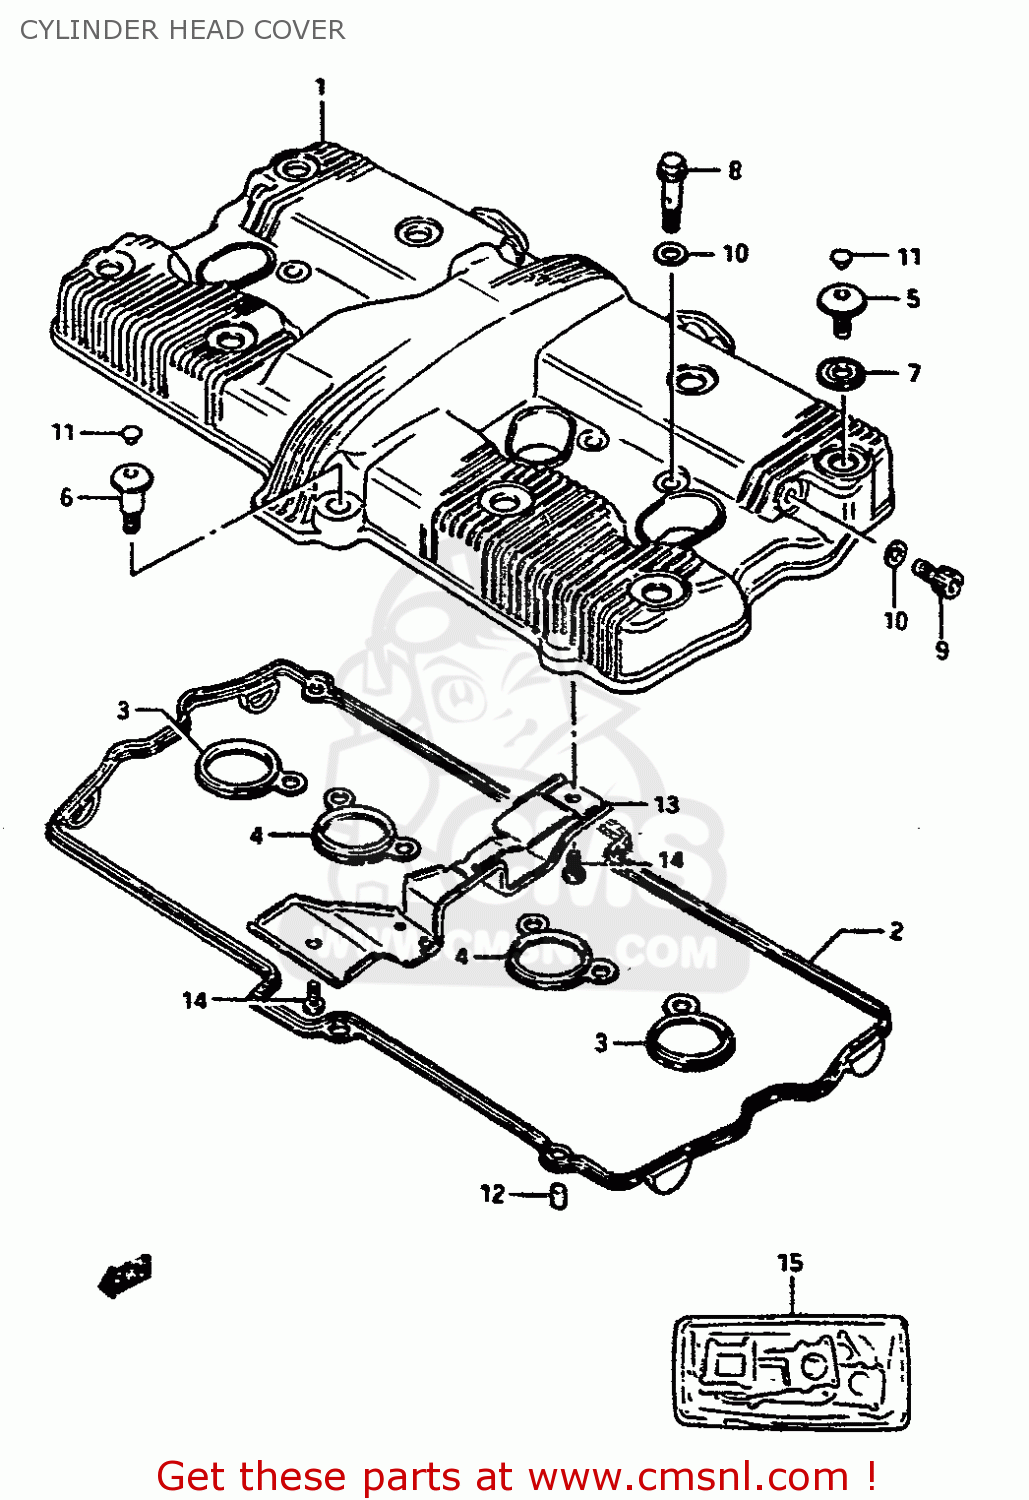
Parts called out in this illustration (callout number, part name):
1	COVER,CYLINDER HEAD
2	GASKET,CYLINDER HEAD COVER (NAS)
3	GASKET (NAS)
4	GASKET,HEAD COVER NO.3 (NAS)
5	BOLT(7X17.5)
6	BOLT(7X31)
7	WASHER
8	BOLT,UNION 8X35
9	PLUG, HEAD COVER
10	GASKET 8.2X14X1 (NAS)
11	CAP(OD:10)
12	PIN
13	COVER,BREATHER
14	BOLT 5X12
15	GASKET SET
